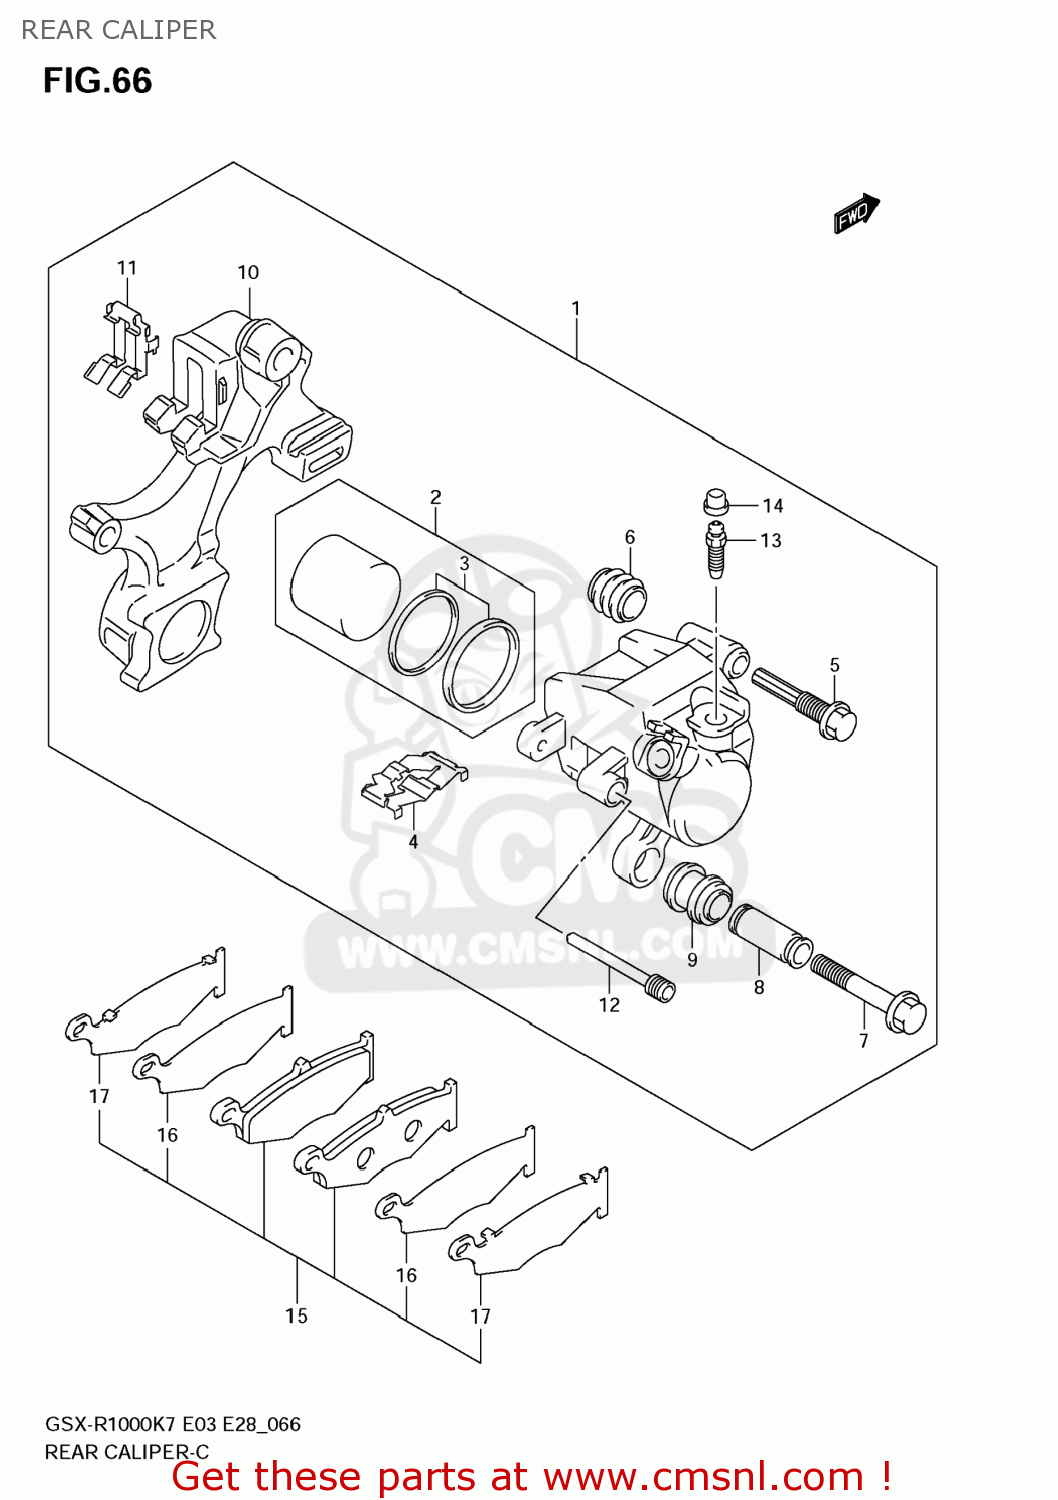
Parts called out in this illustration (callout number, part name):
1	CALIPER ASSY,RR
2	PISTON SET
3	SEAL SET,PISTON
4	SPRING,PAD
5	PIN,BOLT
6	BOOT,AXLE
7	BOLT
8	SLEEVE
9	BOOT,SLEEVE
10	BRACKET
11	RETAINER
12	PIN,PAD
13	BLEEDER
14	CAP,BLEEDER PLUG
15	PAD & SHIM SET (NAS)
16	INSULATOR
17	SHIM
